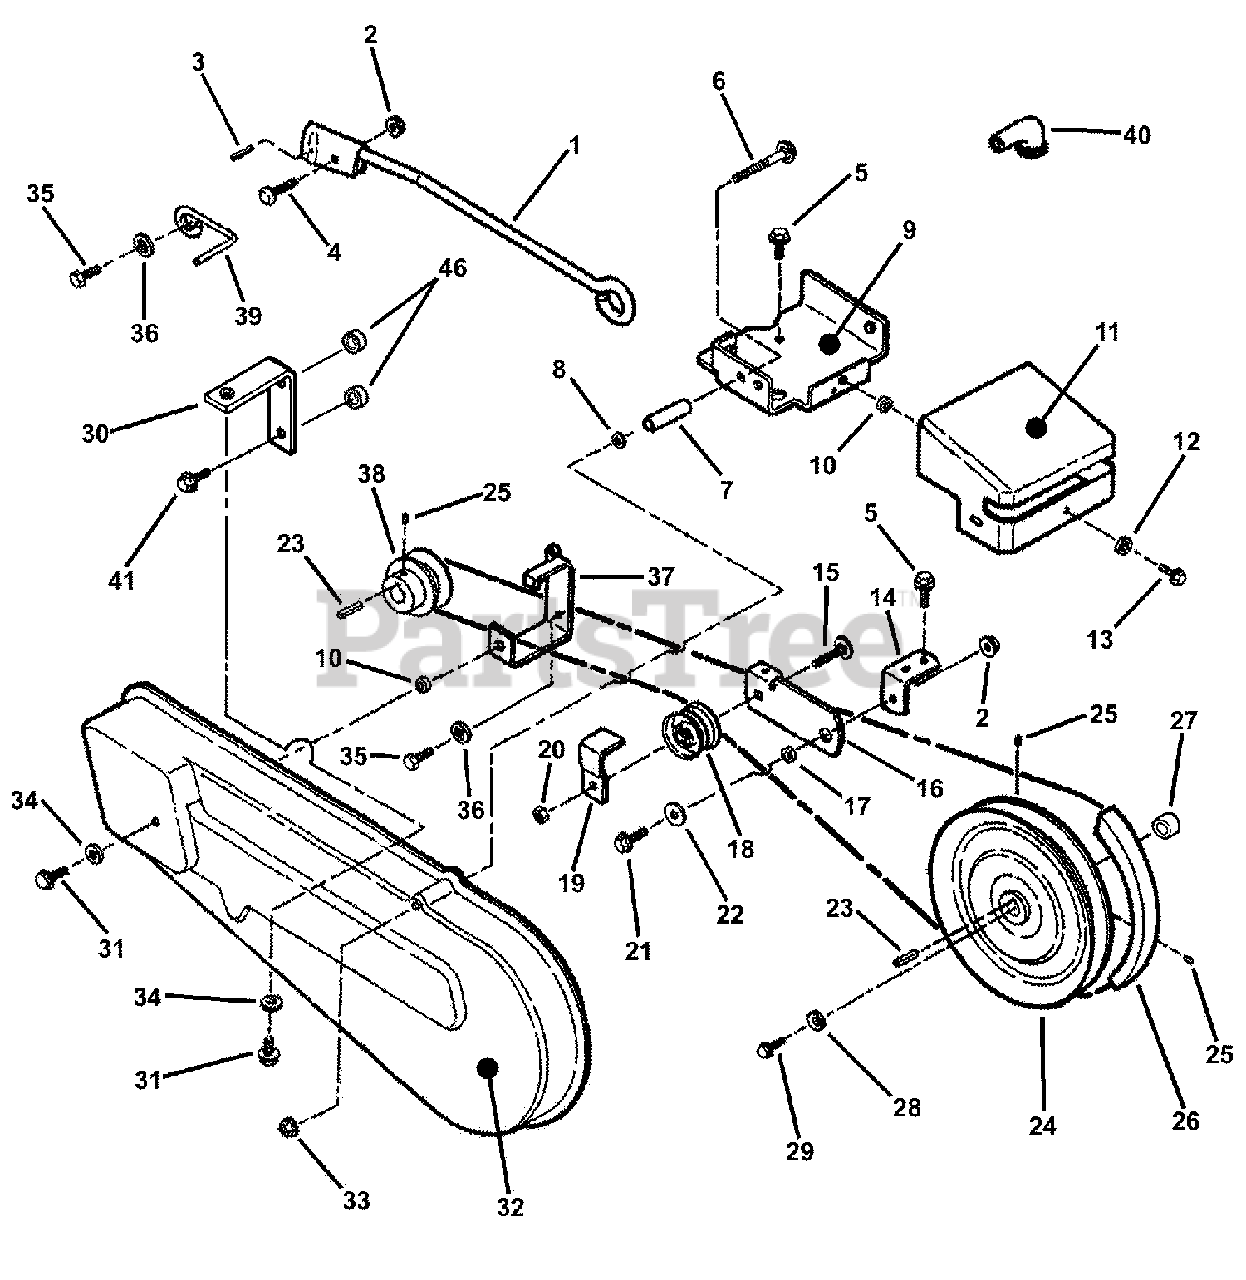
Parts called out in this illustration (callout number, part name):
1	WELDMENT, Shift Lever
2	NUT, 5/16-18 Hex Flange Lock
3	ROLL PIN 3/16 x 1"
4	BOLT, 5/16-18 x 3/4" Square Neck Carriage GR5
5	SCREW, 5/16-18 x 5/8" Hex Washer Self-Tap
6	BOLT, 5/16-18 x 2-1/2" Short Neck Carriage GR5
7	TUBE, 3/8" I.D. x 1-7/8" Long
8	RETAINER, 5/16" Bolt (Black)
9	PLATE, Shift
10	BUSHING, Rubber
11	COVER, Shift
12	WASHER, 1/4" Flat
13	SCREW, 1/4-20 x 3/4" Hex Washer Self-Tap
14	BRACKET, Idler Pivot (shown)
15	BOLT, 3/8-16 x 1-1/2" Flat Head Carriage
16	BRACKET, Idler Arm (shown)
17	SPACER, 5/16" I.D.
18	PULLEY, Idler ( 2" Outside Diameter)
19	GUIDE, Idler
20	NUT, 3/8-16 Hex Center Lock GR5 or B
21	BOLT, 5/16-18 x 5/8" Hex Flange Lock GR5
22	WASHER, 11/32" Flat
23	KEY, 3/16 Sq. x 3/4" Long
24	PULLEY, Driven (9" Outside Dia.)
25	SCREW, 5/16-18 x 5/16" Hex Set
26	BELT, Drive (4L Kevlar 19.09" effective length)
27	SPACER, 5/8" Internal Dia.
28	WASHER, 1/4" Belville
29	SCREW, 1/4-20 x 1/2" Hex Washer Self-Tap
30	BRACKET, Belt Cover- IRT
31	SCREW, 5/16-18 x 5/8" Hex Washer Self-Tap
32	COVER, Belt
33	NUT, 5/16-18 Hex Large Flange Center Lock
34	WASHER, 5/16" Flat
35	SCREW, 5/16-24 x 1/2" Hex Head Cap GR5
36	WASHER, 5/16" Internal Tooth Lock
37	GUIDE, Belt
38	PULLEY, Engine (2-1/2" Outside Dia.)
39	GUIDE, Belt (Finger)
40	BOOT, Spark Plug
41	SCREW, 5/16-18 x 1" Hex Washer Self-Tap
46	SPACER, .340 I.D. x .63 O.D. x .310 Thick
